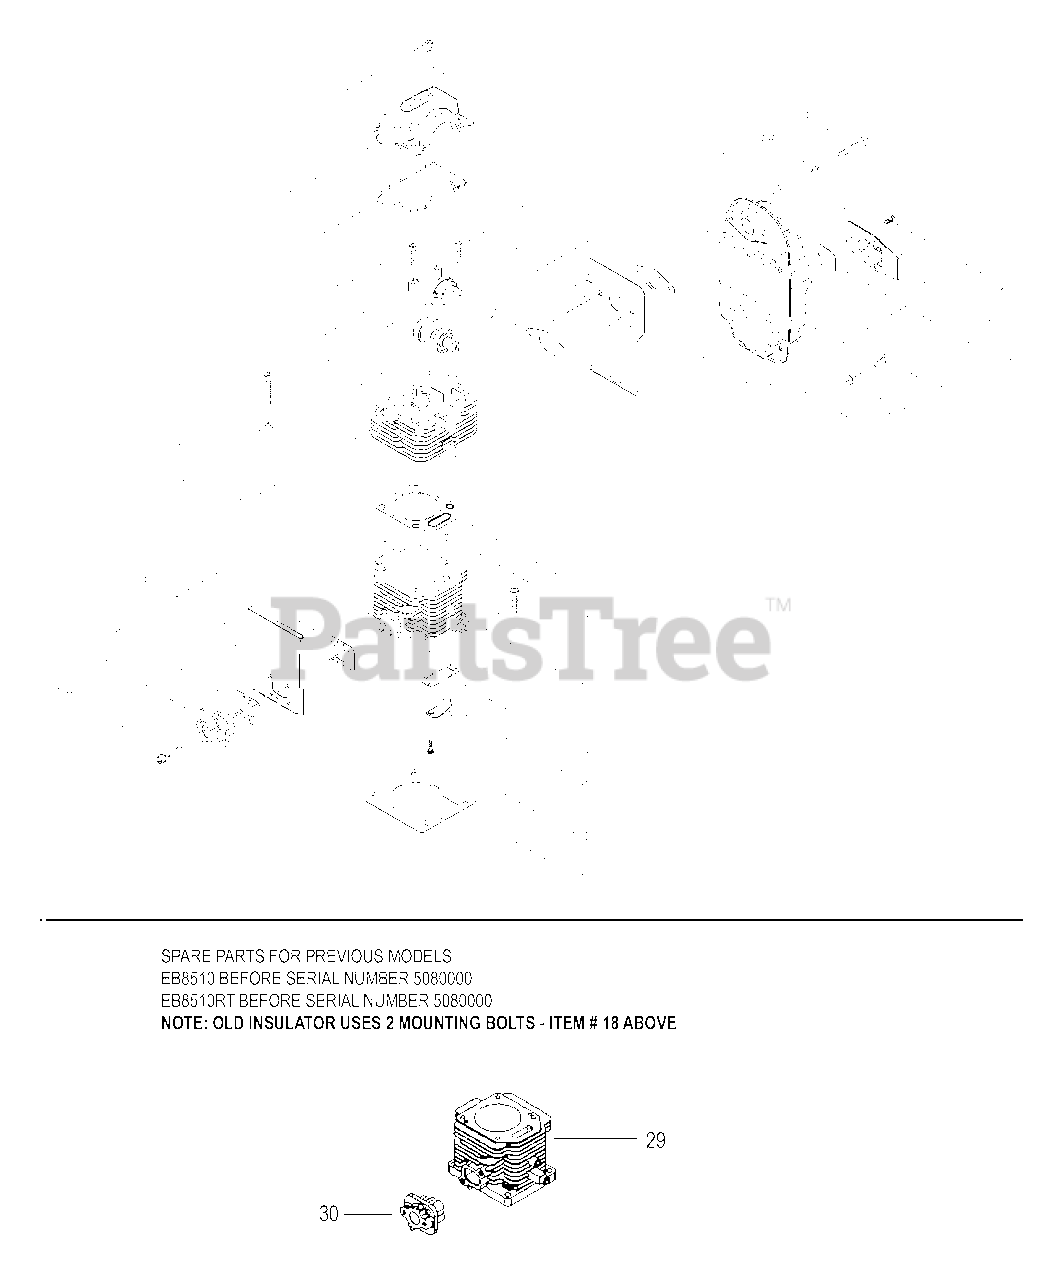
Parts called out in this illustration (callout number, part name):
1	CYLINDER HEAD ASSY
2	BOLT M5×22
3	GASKET
4	BOLT 6×35
5	WASHER 11×6.4×1.5
6	COVER, VALVE
7	GASKET
8	BOLT 5×14
9	CYLINDER
10	GASKET, CYLINDER
11	BOLT 6×25
12	VALVE ASSY, REED
13	GASKET, REED VALVE
14	SCREW M4×14
15	INSULATOR
16	SHIELD ASSY, INTAKE HEAT
17	GASKET, INTAKE
18	BOLT SS M5×30
19	PIN, LOCATING Ø4×8
20	MUFFLER ASSY
21	SCREEN, SPARK ARRESTER
22	GUIDE, EXHAUST
23	SCREW M5×8
24	DEFLECTOR ASSY, EXHAUST HEAT
25	GASKET, EXHAUST
26	BOLT SS M6×35
27	BOLT 6×16
28	WASHER 6.5×11.5×0.8
29	CYLINDER
30	INSULATOR
